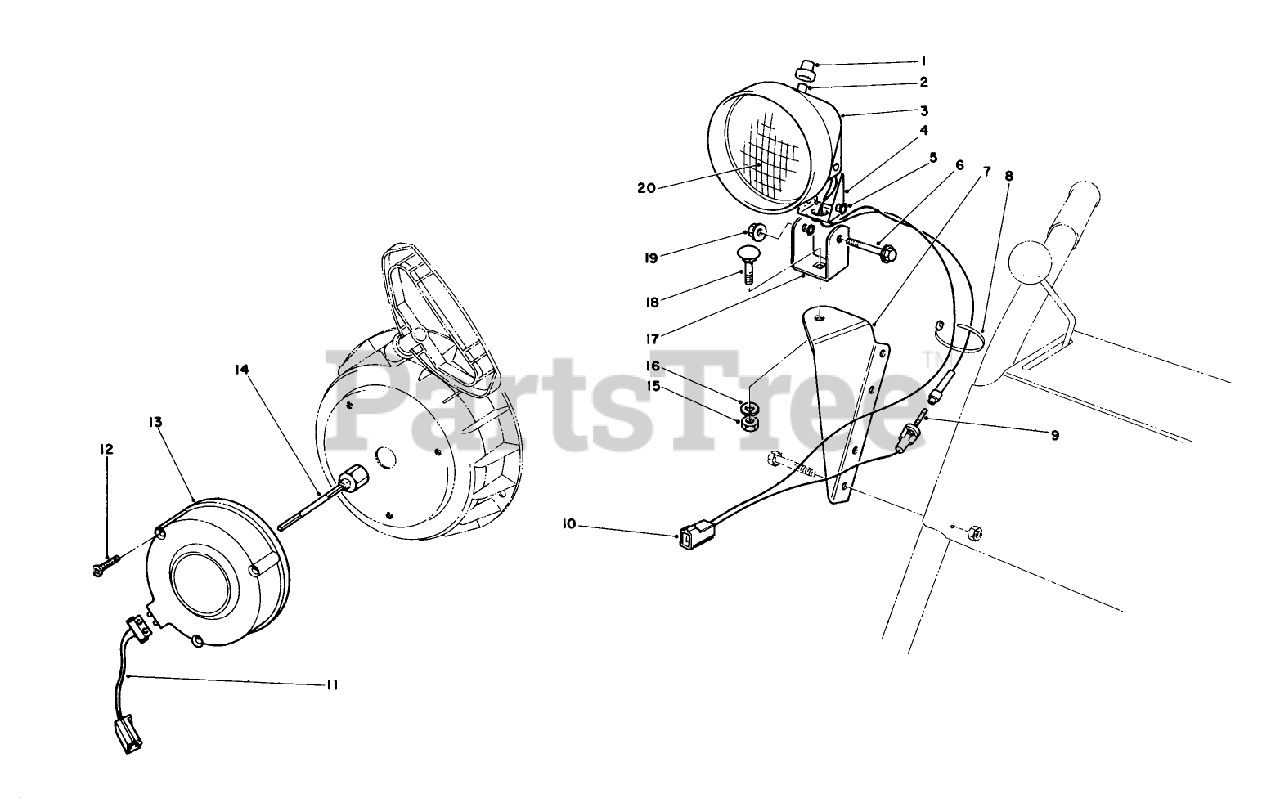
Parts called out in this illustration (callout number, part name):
1	BOOT-SWITCH
5	WASHER-LOCK
6	SCREW-HH
7	MOUNT-LAMP
8	TIE-CABLE
9	Fuse-7 1/2 Amp.
10	WIRE ASM
13	TECUMSEH 1A183-69
15	NUT-HEX
16	WASHER-LOCK
18	BOLT-CARR
19	NUT-HF
